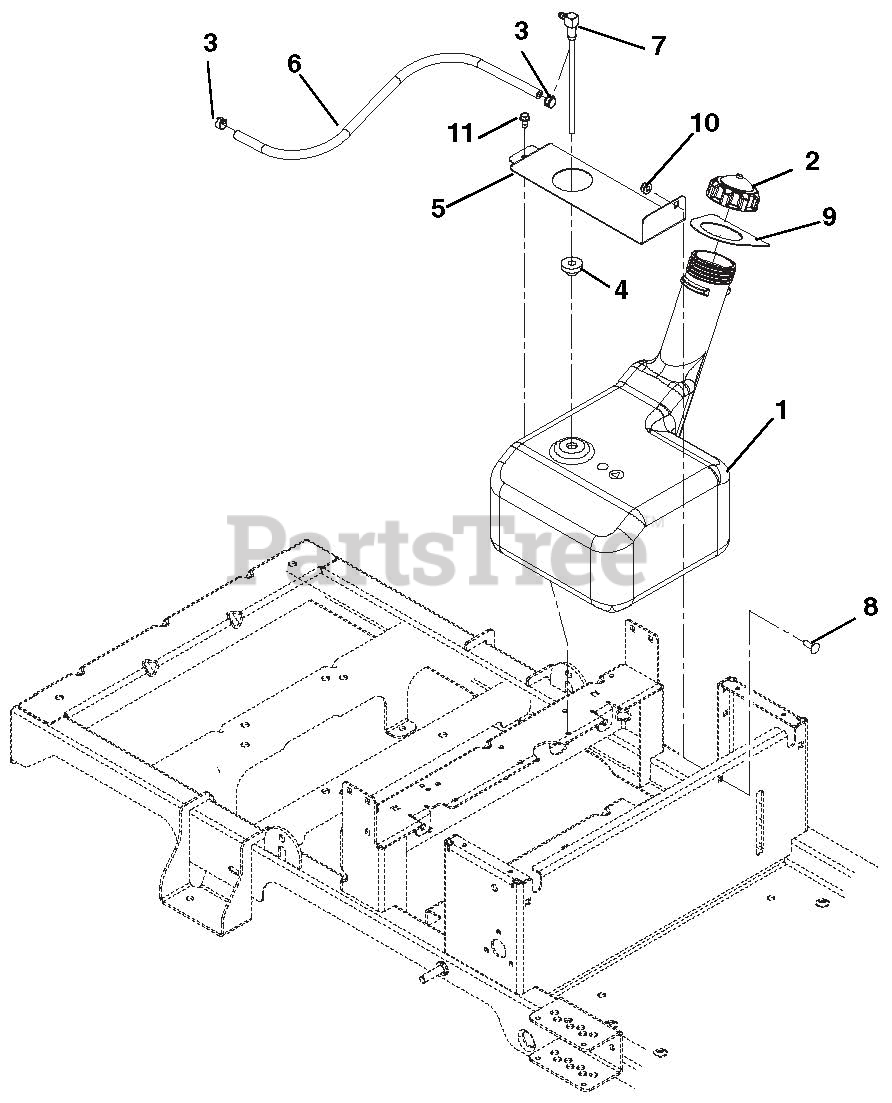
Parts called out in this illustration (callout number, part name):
1	FUEL TANK
2	FUEL CAP
3	CLAMP, FUEL LINE
4	BSHG-FLG .375 X 1.062 X .625 R
5	BRKT, TANK STRAP
6	HOSE, .25 LOW-PERM BULK GAS
7	ASSY-PICKUP, FUEL 6.5L
8	@BLT-RDHDSQNK .25-20X.75 G5YZ
9	SEAL-TANK NECK
10	@NUT-LK-NYL-FLG .25-20 YWZC
11	@SCR-TAP .25-20X.50 HWH TR YWZ
